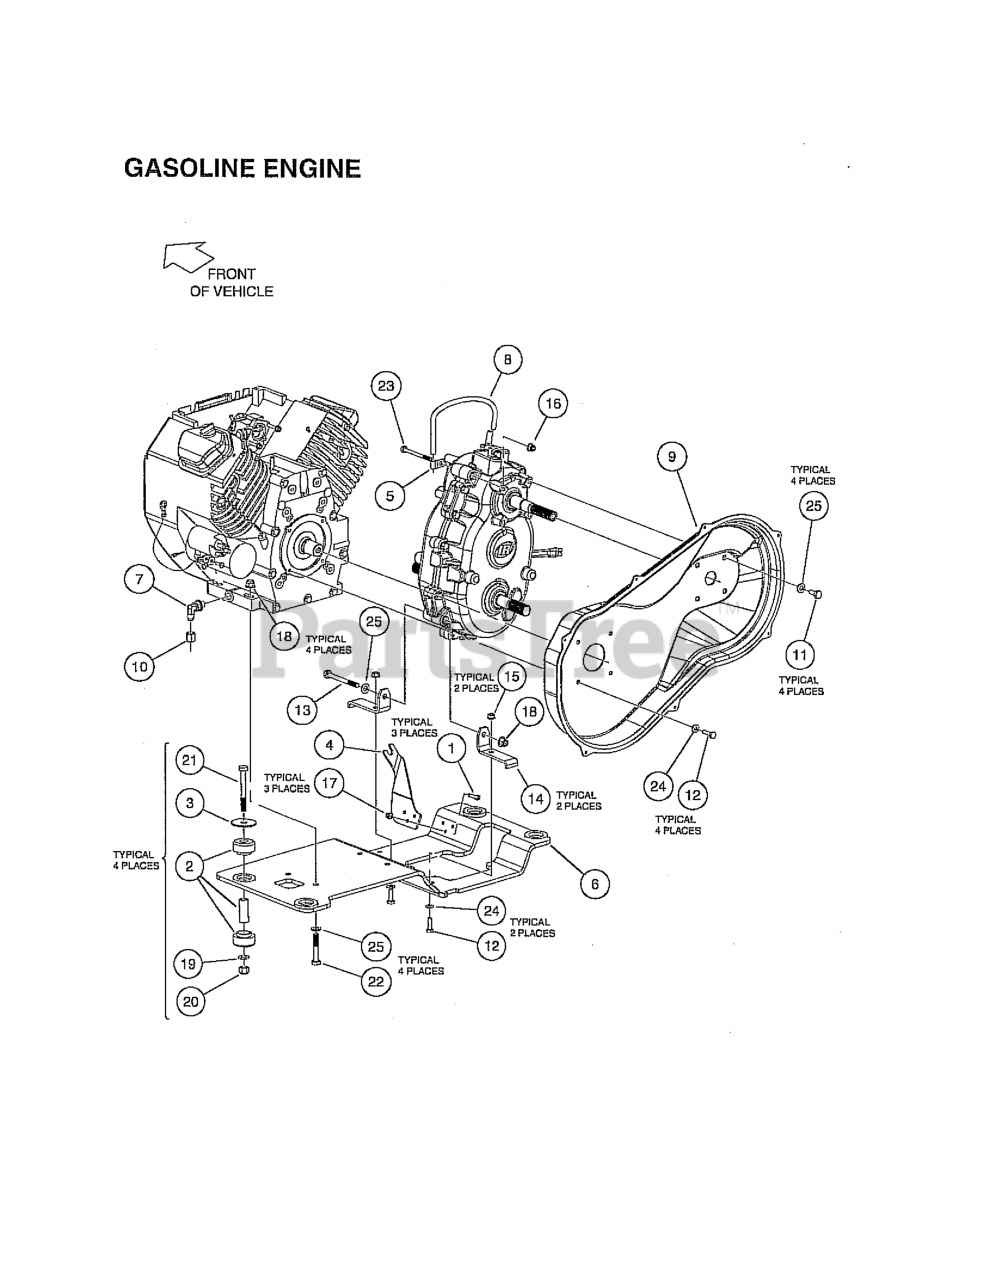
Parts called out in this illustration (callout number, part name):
4	BRACKET, FNR TRANS CABLE
5	P-CLAMP, INSULATED .312 IN
6	PLATE, ENG MTG, WELD, HONDA
7	FITTING, 90 OIL DRAIN
8	HOSE, VENT, TRANSMISSION
9	COVER, CVT INNER, HONDA
10	CAP, OIL DRAIN
11	BOLT, M10 X 1.5 X 20 LOCTITE
12	BOLT, M8 X 1.25 X 25 LOCTITE
13	BOLT, M10 X 1.5 X 100 LOCTITE
14	BRACKET, TRANSMISSION MTG
15	NUT FLG, M8 X 1.25 MECH DEF
16	LOCK NUT, FLG M8 X 1.25 NYLON
17	NUT FLG, M6 X 1.0 NYLON
18	NUT FLG M10 X 1.5 NYLON
19	WASHER, M12 HARD
20	LOCKNUT, M12X1.75 NYLON INSERT
21	BOLT, M12 X 1.75 X 90
22	BOLT, M10 X 1.5 X 60
23	BOLT, M8 X 1.25 X 80
24	WASHER, M8 HARD
25	WASHER, M10 HARD
